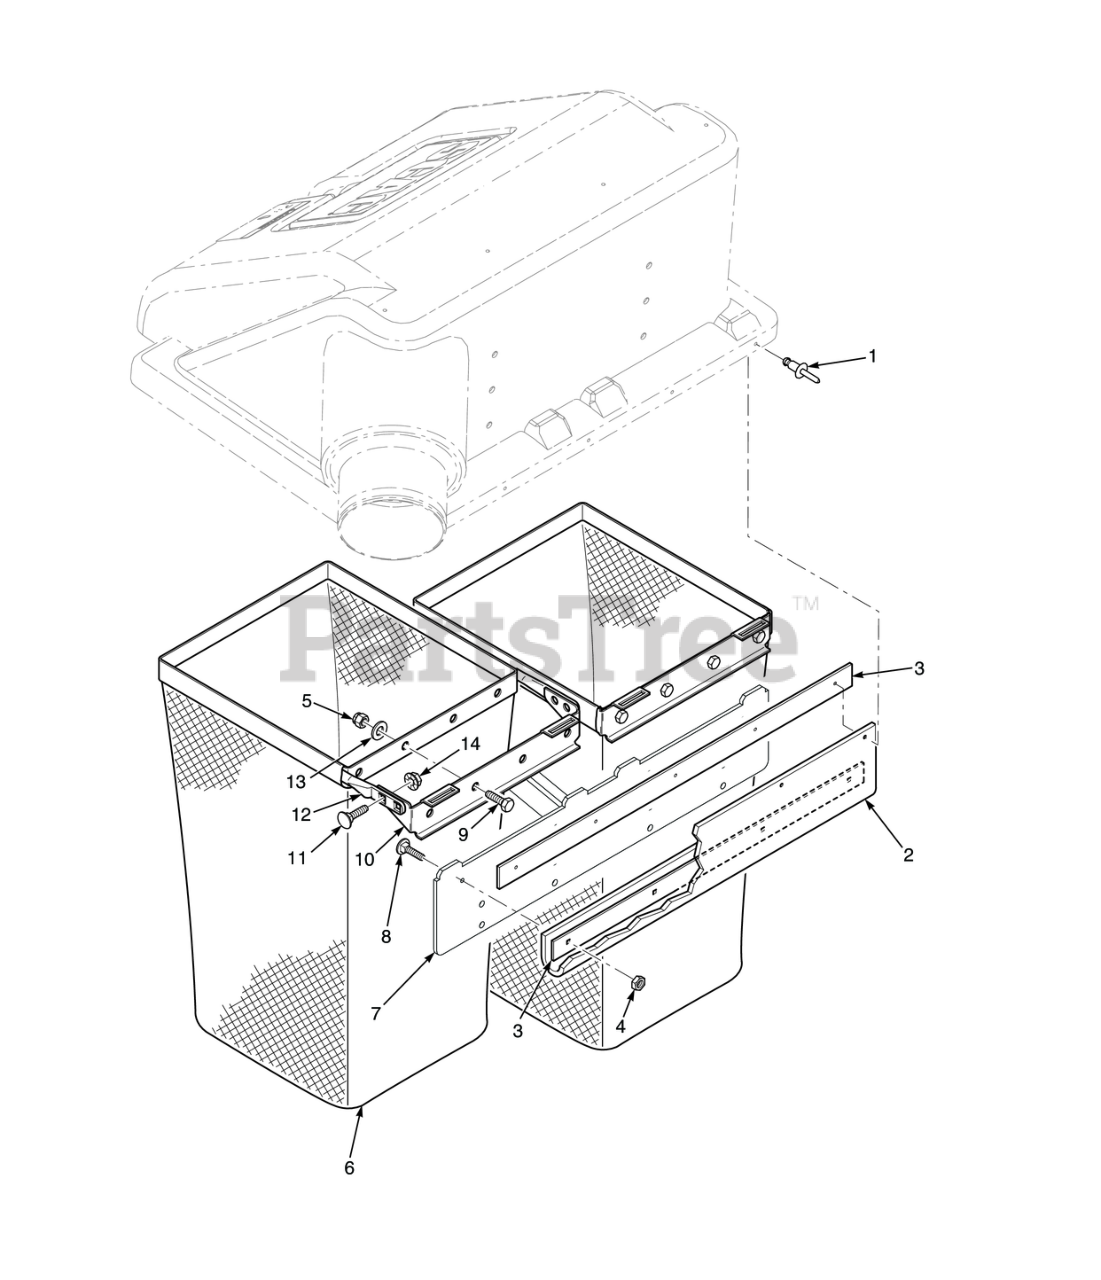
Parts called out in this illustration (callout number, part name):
1	Pop Rivet, 3/16 x .652"
2	Diode (part of wire harness)
3	Retainer, Seal
4	Bolt, Hex Hd. 1/2-13 x 9-1/2"
5	HEX NUT, ELASTIC STOP LOCK, 5/16-18
6	Bag Assembly
7	Frame Weldment, Bag Support
8	BOLT, HEX HEAD, 1/4-20 X 3/4 GR.5
9	BOLT, SERRATED FLANGE HEX HEAD 5/16-18 X 3/4"
10	Mount, Bag Frame Tube
11	Bolt, 5/16-18 x .75 RHSN Carriage
12	Tube, Bag Support
13	Flatwasher, 5/16-.375 x .875 x .083 (35BV & 37BV-EFI)
14	Nut, Serrated Flange 5/16-18 (Right Front Engine Mounting, Briggs and Kohler Only)
